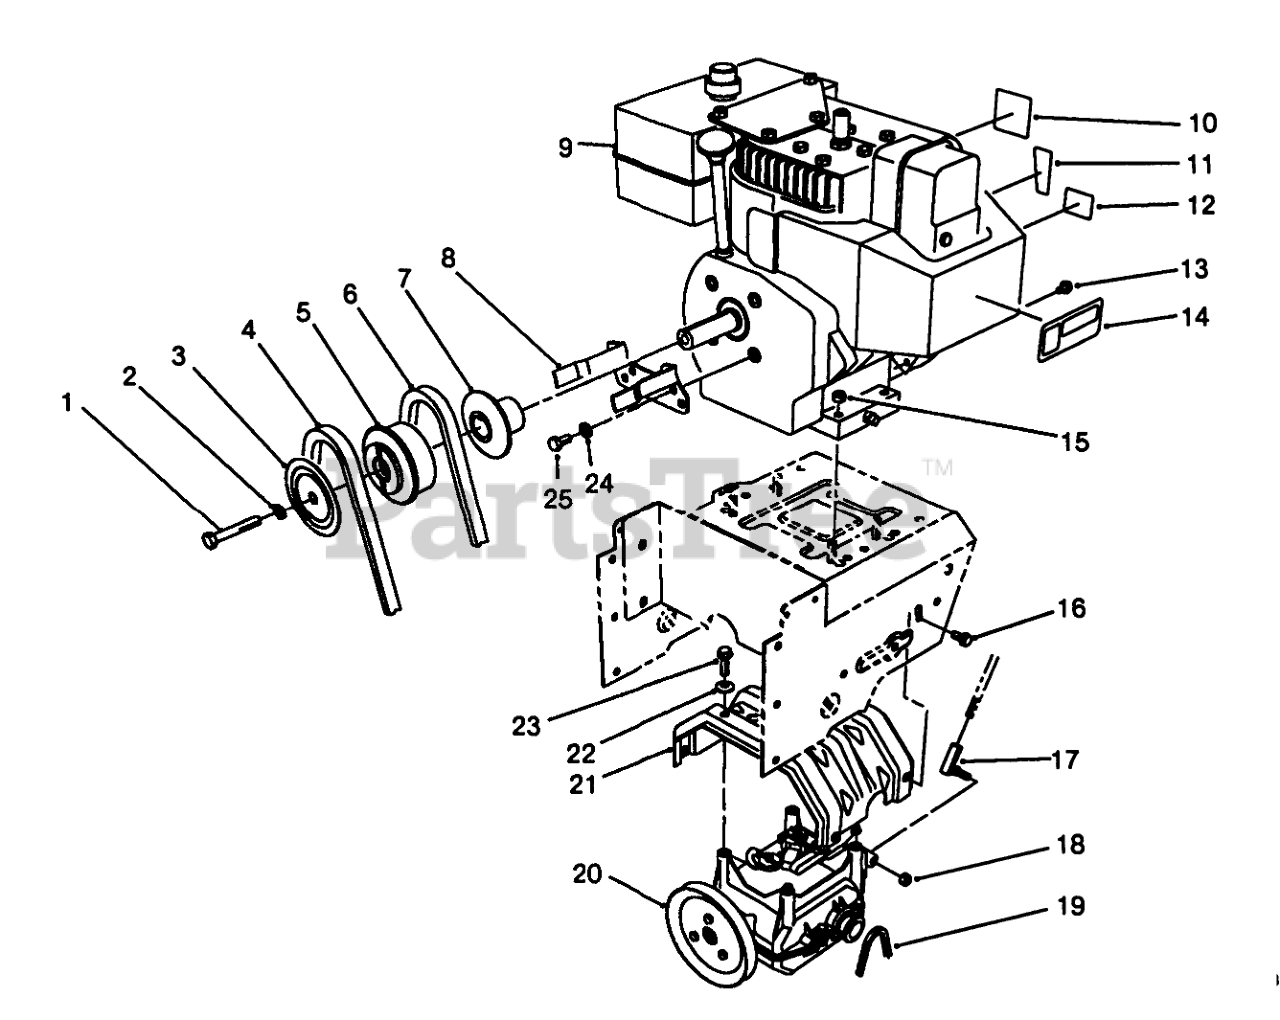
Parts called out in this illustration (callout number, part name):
1	SCREW-HH
2	WASHER-LOCK
3	SHEAVE-HALF, IMPELLER
4	V-BELT
5	PULLEY-ENGINE, CENTER
6	V-BELT-TRACTION
7	SHEAVE-HALF, TRACTION
8	Guide-Belt
10	DECAL-PRIMER
11	DECAL-THROTTLE
12	DECAL-CHOKE
13	SCREW-HWH
14	Decal-Hot
15	NUT-HF
16	SCREW-HHF
17	JOINT-BALL
18	NUT-LOCK
19	CHAIN
20	Transmission Assembly
21	Frame-Transmission
22	WASHER-SPRING
23	SCREW-HWHTF
24	WASHER-LOCK
25	SCREW-HH
